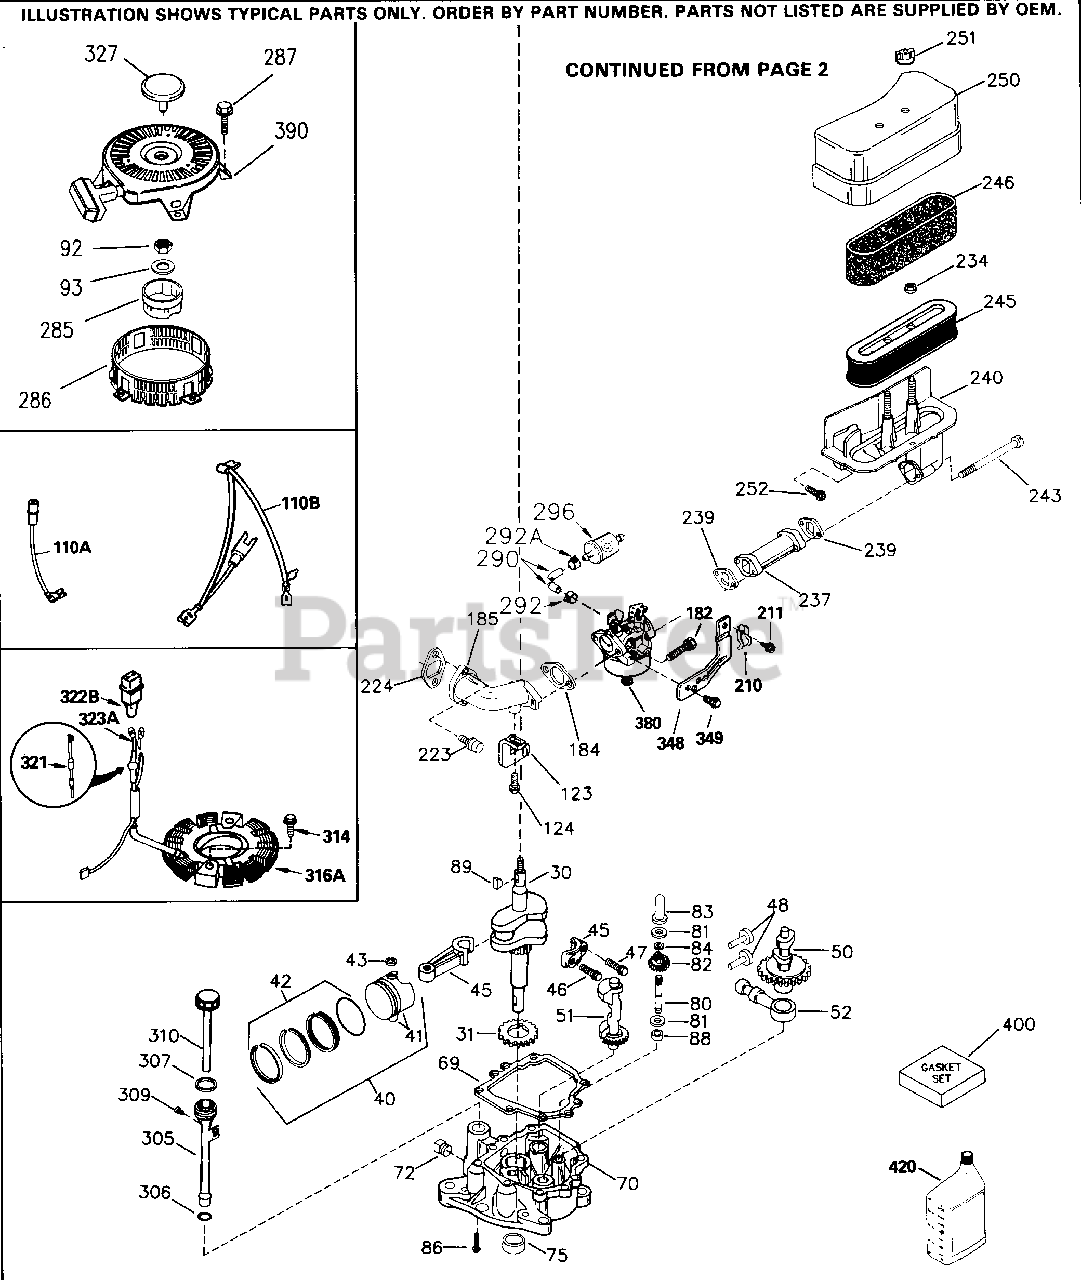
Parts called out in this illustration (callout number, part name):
28	Lock Nut, 8-32
30	Crankshaft
31	Counterbalance Gear
40	Piston, Pin & Ring Set (Std.)
40	Piston, Pin & Ring Set (.010" OS)
40	Piston, Pin & Ring Set (.020" OS)
41	Piston & Pin Ass'y. (Std.) (Incl. 43)
41	Piston & Pin Ass'y. (.010" OS) Incl. 43
41	Piston & Pin Ass'y. (.020" OS) Incl. 43
42	Ring Set (Std.) (3-5/16")
42	Ring Set (.010" OS)
42	Ring Set (.020" OS)
43	Piston Pin Retaining Ring
45	Connecting Rod Ass'y. (Incl. 46 & 47)
46	Connecting Rod Bolt
47	Connecting Rod Bolt
48	Valve Lifter
50	Camshaft (MCR)
51	Counterbalance Weight
52	Oil Pump Ass'y.
69	* Mounting Flange Gasket
70	Mounting Flange (Incl. 72, 72A, 75 & 80)
72	Oil Drain Plug
75	Oil Seal
80	Governor Shaft
81	WASHER
82	Governor Gear Assembly
83	Governor Spool
84	Retaining Ring
86	Screw, 1/4-20 x 1-3/16"
89	Flywheel Key
92	Lock Washer
93	Flywheel Nut
123	Intake Pipe Brace
124	Screw, 1/4-20 x 5/8"
182	Screw, 1/4-20 x 27/32"
184	* Carburetor To Intake Pipe Gasket
185	Intake Pipe
210	Conduit Clip
211	Screw, 10-32 x 3/8"
212A	Bushing
223	Screw, Torx T-30, 5/16-18 x 7/8"
224	* Intake Pipe Gasket
234	Nut & Lock Washer, 1/4-20
237	Air Filter Adapter
238	Screw, 10-32 x 5-1/4"
239	* Air Cleaner Gasket
240	Air Cleaner Body (Incl. 239)
245	Air Filter (Incl. 234) also available in Packaged Part #740015B
245A	Pre-Cleaner Air Filter also available in Packaged Part #740015B
250	Air Cleaner Cover
251	Wing Nut, 1/4-20
286	Cup & Screen
290	Fuel Line
292	Fuel Line Clamp
296	Fuel Filter (Incl. 292) also availabl e as Packaged Part #740003B
305	Oil Fill Tube
307	"O" Ring
308	Fill Tube Clip
308A	Fill Tube Clip
310	Dipstick
314	Screw, 1/4-20 x 3/4"
315	Alternator Coil (3/5 Split) Incl. 321 , 322,323
337	Deflector
380	Carburetor (Incl. 184)
400	* Gasket Set (Incl. items marked PK in notes) Incl. part #'s 27896 (2), 332 63 (1), 33629 (2), 34265 (1), 35317 ( 1), 35762 (2), 35946 (1), 35352 (1), 35958 (1)
420	SAE 30 4-Cycle Engine Oil (Quart)
